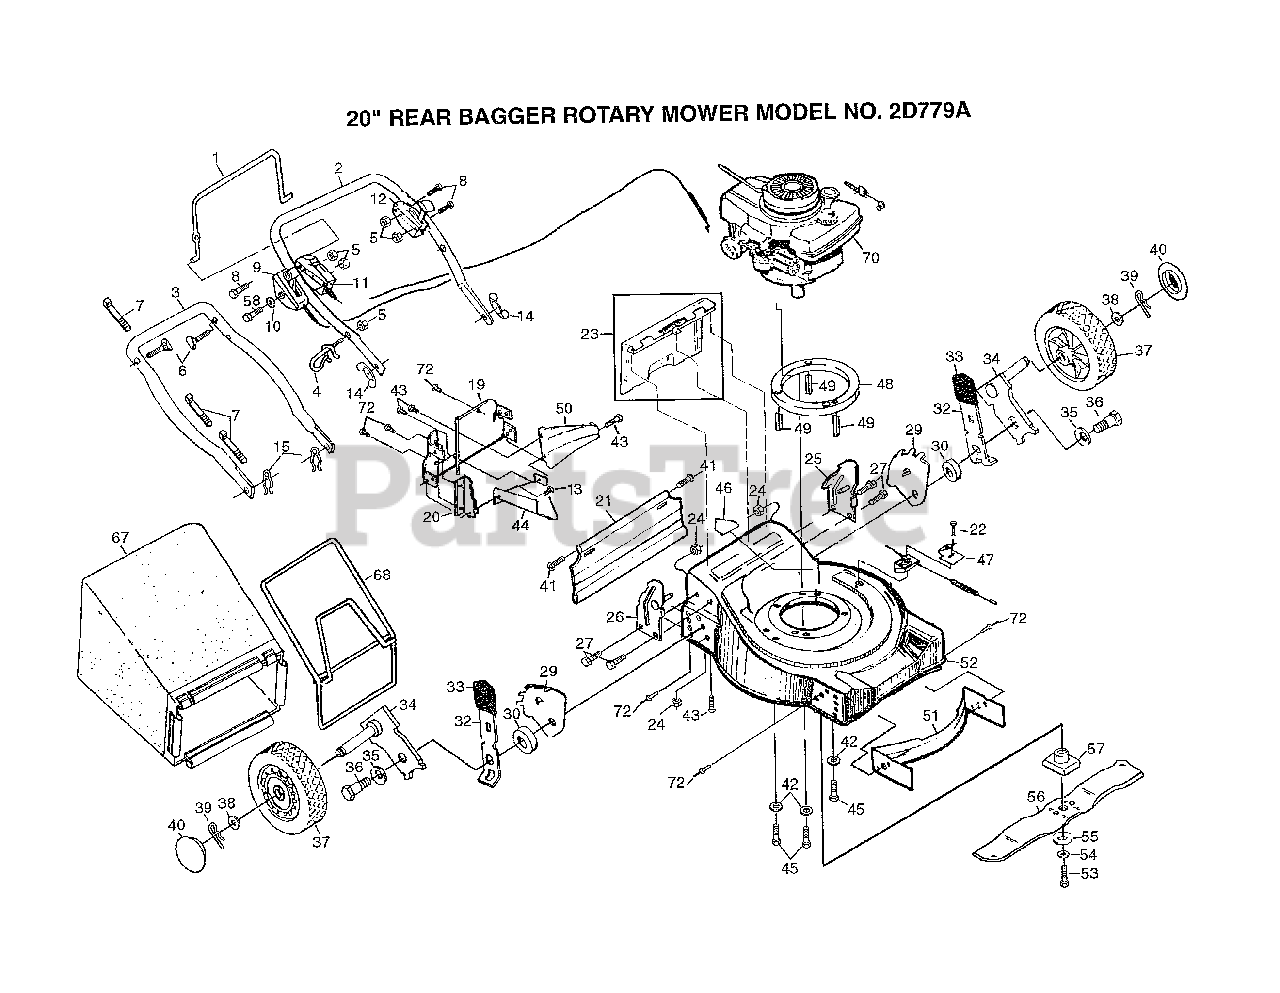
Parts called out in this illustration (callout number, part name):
1	CONTROL BAR
4	ROPE GUIDE
6	BOLT.HANDLE.LM
10	WASHER PM
11	CABLE MZR E/S
12	DRIVE CONTROL
13	SCREW PM
14	"NUT,WING PM"
15	HAIRPIN COTTER
19	"PLATE.BACK.20"""
22	"SCREW, HEX PM"
23	"KIT, REAR DOOR PM"
24	LOCKNUT PM
27	SCREW
29	BRACKET.ADJ.9POS.
32	SPRING SELECTOR
33	KNOB PM
34	AXLE ARM
35	"WASHER, BELLEVIL."
36	BOLT SHLD 3/8-16
38	WASHER
39	RETAINER CLIP PM
40	HUB CAP
41	HINGE SCREW
43	SCREW
44	DISCHARGE GUARD
45	SCREW
46	DECAL HYT
47	BRKT DRV COV
48	ENGINE SPACER
50	REAR BAFFLE
52	KIT.HSG.20RD.FWBD
53	SCREW
54	LOCKWASHER
55	"WASHER,HARDEN"
56	BLADE.STAND.20INC
57	ADAPTOR.BLADE.LM
67	GRASS BAG
68	CATCHER FRAME
72	BLIND RIVET
